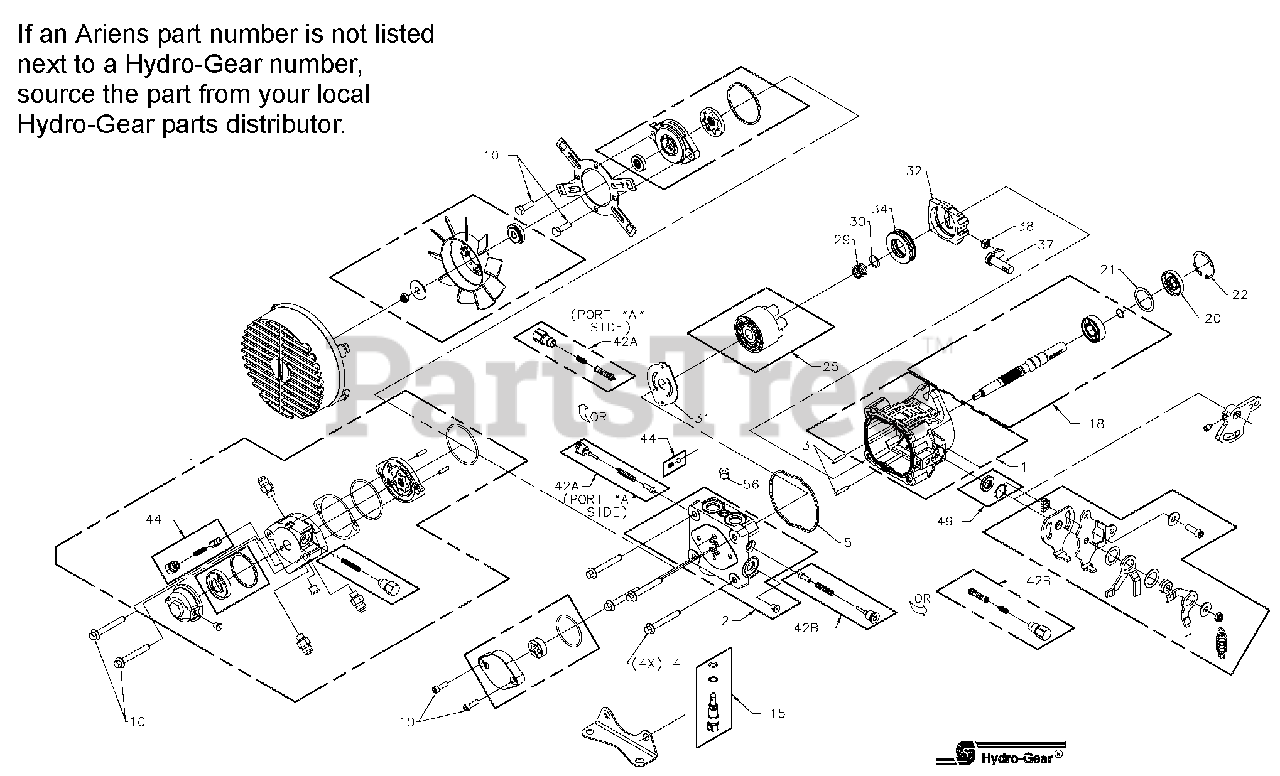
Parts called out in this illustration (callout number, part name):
1	KIT, HSG
2	KIT, END CAP W/PPT & STD
3	PIN, .219X1
4	HFHCS M8X60
5	KIT, CHG PUMP
10	SCREW, CAP M6X1X25
15	KIT, BYPASS VALVE
18	KIT, PUMP SHAFT 15MM KEYW
20	SEAL, LIP 17X40X7
21	WASHER 1.23X1.56X.04
22	RING, RET 1.56 INT
25	KIT, 10 CC BLOCK
29	SPRING. BLOCK
30	WASHER. THRUST .59 X .79 X .04
31	PLATE, VALVE
32	SWASHPLATE. VARIABLE
34	BEARING. THRUST 30 X 52 X 13
37	ARM, TRUNNION 10 CC
38	GUIDE. SLOT
42	KIT, SHOCK VALVE 200 BAR
44	KIT, CHG RELIEF
49	KIT, PUMP SEAL
56	PLUG 7/16-20 (METAL)
NS	KIT, PUMP SEAL
